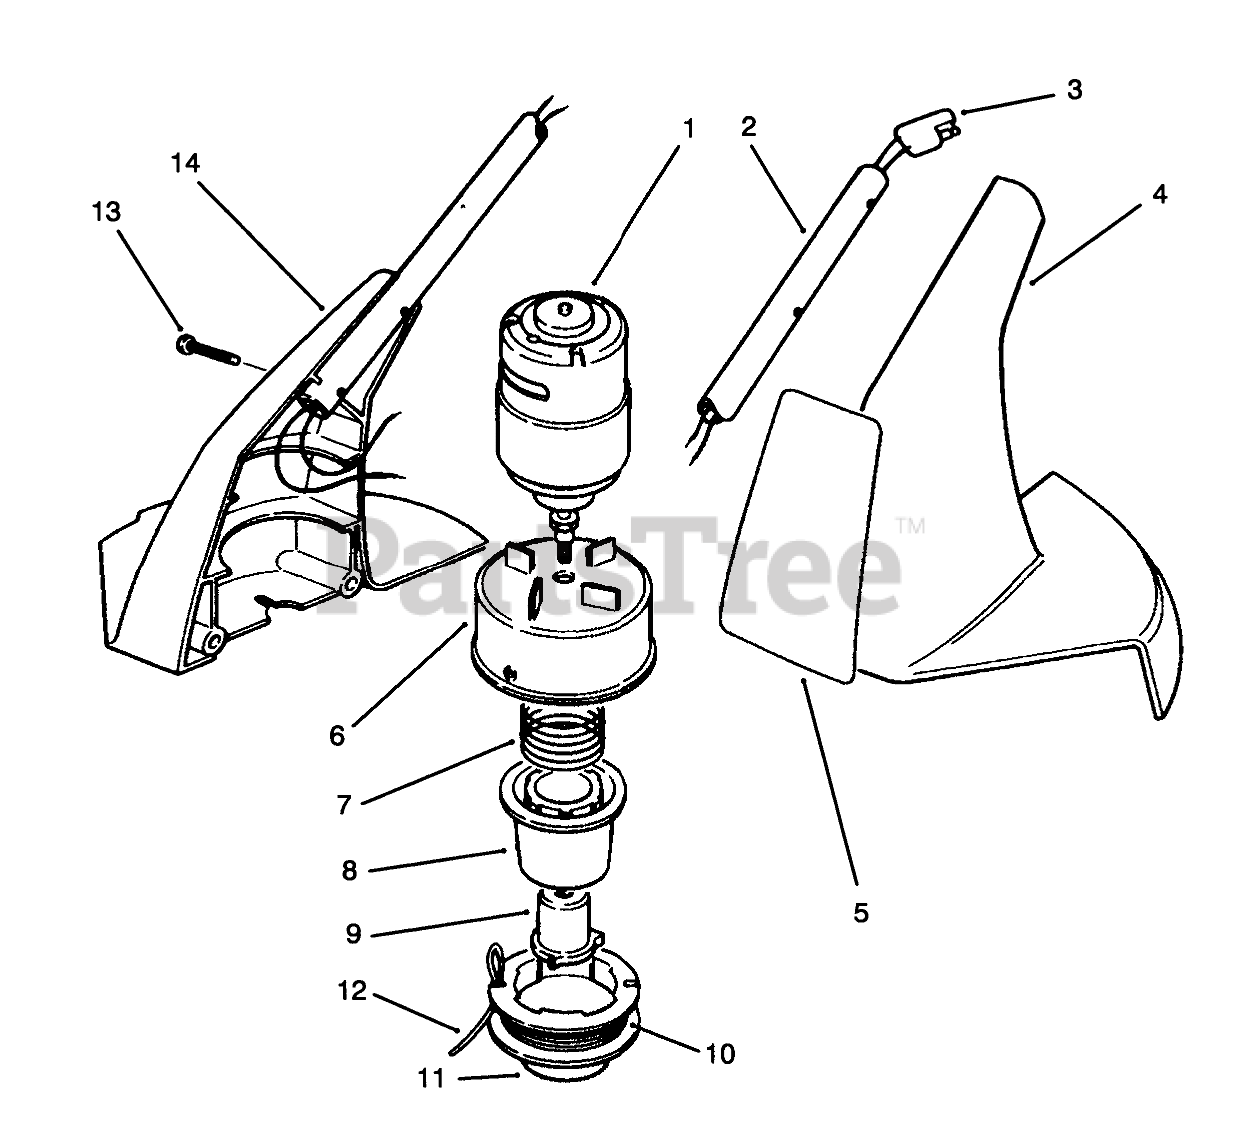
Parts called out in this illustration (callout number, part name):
1	MOTOR ASM
2	HANDLE-EXTENSION
3	WIRING HARNESS-LOWER
4	HOUSING, LH - 7"TRIMMER
5	DECAL - 7" TRIMMER
6	DRUM ASM-4 BLADE
7	SPRING-COMPRESSION
8	CORE - SPOOL
9	DRIVER
10	Line-Cutting 12-.050 Dia. Prewound Spool(Incl. Ref. #11)
11	CAP-SPOOL
12	Filament Line 30-(.050 Dia.)
13	SCREW-PLASTITE
14	Housing-Motor R.H.
